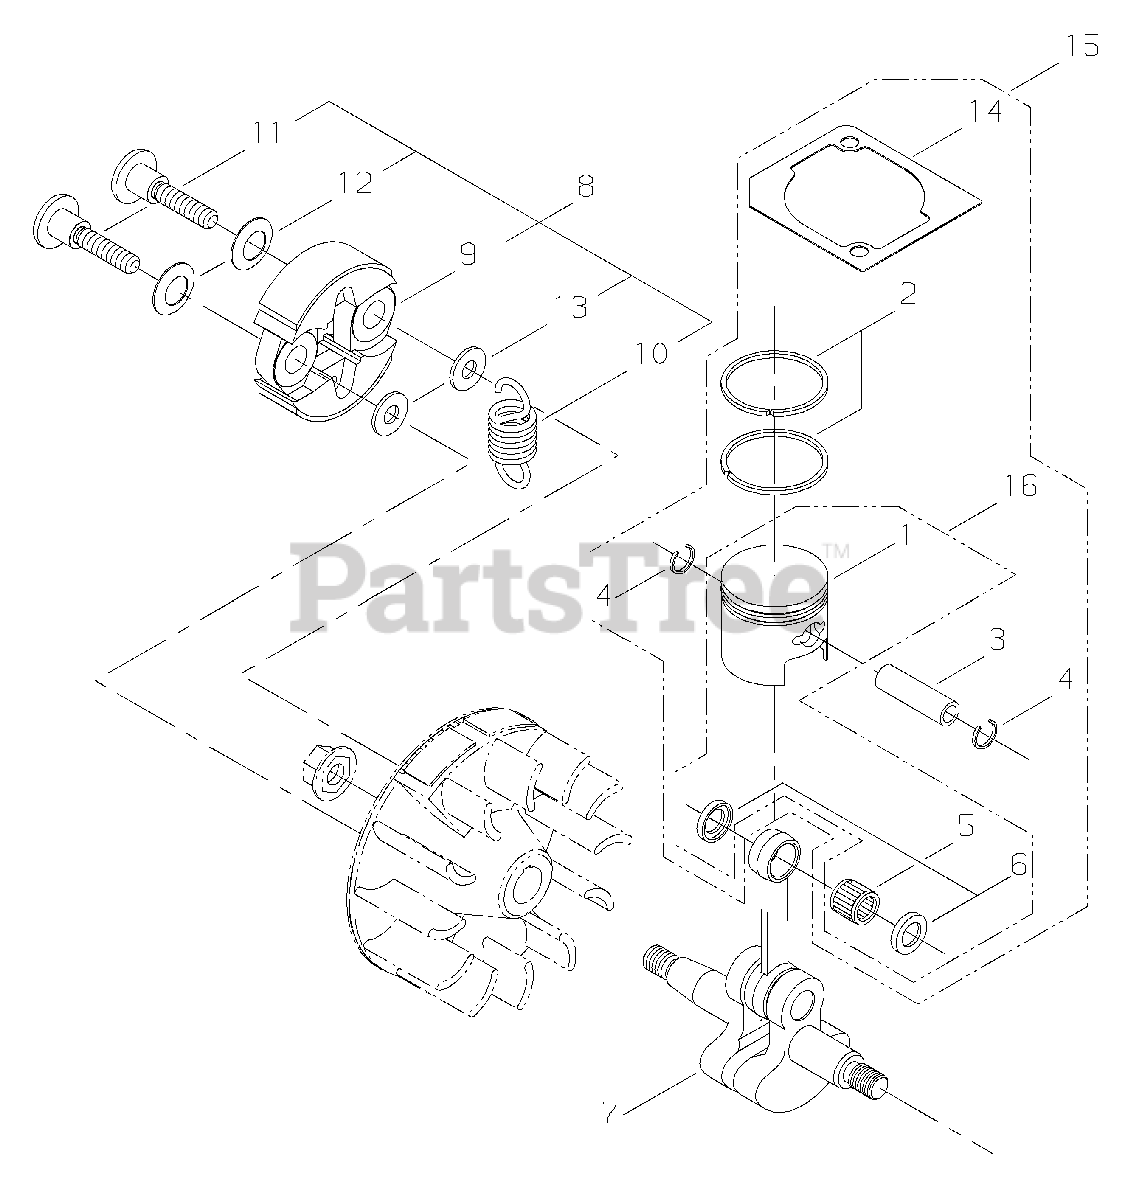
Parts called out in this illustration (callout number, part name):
1	PISTON
2	RING, PISTON
3	PIN, PISTON
3-15	PISTON SET
4	RING, RETAINING
5	BEARING, NEEDLE - 8
6	SPACER, PISTON
7	CRANKSHAFT ASSY
8	CLUTCH ASSY
9	SHOE, CLUTCH
10	SPRING, CLUTCH
11	BOLT, CLUTCH
12	WASHER - SPRING
13	WASHER
14	GASKET, CYLINDER
16	PISTON SET
